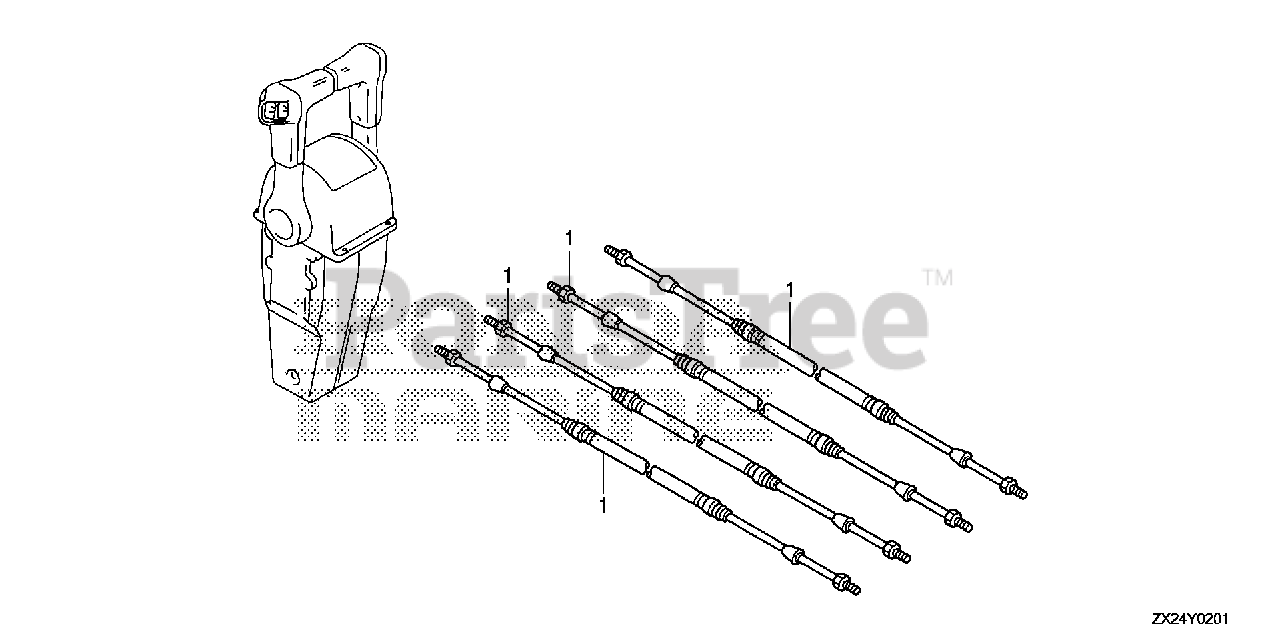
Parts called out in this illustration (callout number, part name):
1	CABLE, REMOTE CONTROL (10') (LOW FRICTION)
1	CABLE ASSY., PUSH-PULL (33C-5FT)
1	CABLE, REMOTE CONTROL (11') (LOW FRICTION)
1	CABLE ASSY., PUSH-PULL (33C-6FT)
1	CABLE, REMOTE CONTROL (12') (LOW FRICTION)
1	CABLE ASSY., PUSH-PULL (33C-7FT)
1	CABLE, REMOTE CONTROL (13') (LOW FRICTION)
1	CABLE ASSY., PUSH-PULL (33C-8FT)
1	CABLE, REMOTE CONTROL (14') (LOW FRICTION)
1	CABLE ASSY., PUSH-PULL (33C-9FT)
1	CABLE, REMOTE CONTROL (15') (LOW FRICTION)
1	CABLE ASSY., PUSH-PULL (33C-10FT)
1	CABLE, REMOTE CONTROL (16') (LOW FRICTION) (NOT AVAILABLE)
1	CABLE ASSY., PUSH-PULL (33C-11FT)
1	CABLE, REMOTE CONTROL (17') (LOW FRICTION)
1	CABLE ASSY., PUSH-PULL (33C-12FT)
1	CABLE, REMOTE CONTROL (18') (LOW FRICTION) (NOT AVAILABLE)
1	CABLE ASSY., PUSH-PULL (33C-13FT)
1	CABLE, REMOTE CONTROL (19') (LOW FRICTION)
1	CABLE ASSY., PUSH-PULL (33C-14FT)
1	CABLE, REMOTE CONTROL (20') (LOW FRICTION) (NOT AVAILABLE)
1	CABLE ASSY., PUSH-PULL (33C-15FT)
1	CABLE, REMOTE CONTROL (21') (LOW FRICTION)
1	CABLE ASSY., PUSH-PULL (33C-16FT)
1	CABLE, REMOTE CONTROL (22') (LOW FRICTION) (NOT AVAILABLE)
1	CABLE ASSY., PUSH-PULL (33C-17FT)
1	CABLE, REMOTE CONTROL (23') (LOW FRICTION)
1	CABLE ASSY., PUSH-PULL (33C-18FT)
1	CABLE, REMOTE CONTROL (24') (LOW FRICTION) (NOT AVAILABLE)
1	CABLE ASSY., PUSH-PULL (33C-19FT)
1	CABLE, REMOTE CONTROL (25') (LOW FRICTION)
1	CABLE ASSY., PUSH-PULL (33C-20FT)
1	CABLE, REMOTE CONTROL (26') (LOW FRICTION)
1	CABLE ASSY., PUSH-PULL (33C-21FT)
1	CABLE, REMOTE CONTROL (27') (LOW FRICTION)
1	CABLE ASSY., PUSH-PULL (33C-22FT)
1	CABLE, REMOTE CONTROL (28') (LOW FRICTION) (NOT AVAILABLE)
1	CABLE ASSY., PUSH-PULL (33C-23FT)
1	CABLE, REMOTE CONTROL (29') (LOW FRICTION)
1	CABLE ASSY., PUSH-PULL (33C-24FT)
1	CABLE, REMOTE CONTROL (30') (LOW FRICTION) (NOT AVAILABLE)
1	CABLE ASSY., PUSH-PULL (33C-25FT)
1	CABLE, REMOTE CONTROL (31') (LOW FRICTION)
1	CABLE ASSY., PUSH-PULL (33C-26FT)
1	CABLE, REMOTE CONTROL (32') (LOW FRICTION) (NOT AVAILABLE)
1	CABLE ASSY., PUSH-PULL (33C-27FT)
1	CABLE, REMOTE CONTROL (33') (LOW FRICTION)
1	CABLE ASSY., PUSH-PULL (33C-28FT)
1	CABLE, REMOTE CONTROL (34') (LOW FRICTION) (NOT AVAILABLE)
1	CABLE ASSY., PUSH-PULL (33C-29FT)
1	CABLE, REMOTE CONTROL (35') (LOW FRICTION)
1	CABLE ASSY., PUSH-PULL (33C-30FT)
1	CABLE ASSY., PUSH-PULL (33C-31FT)
1	CABLE ASSY., PUSH-PULL (33C-32FT)
